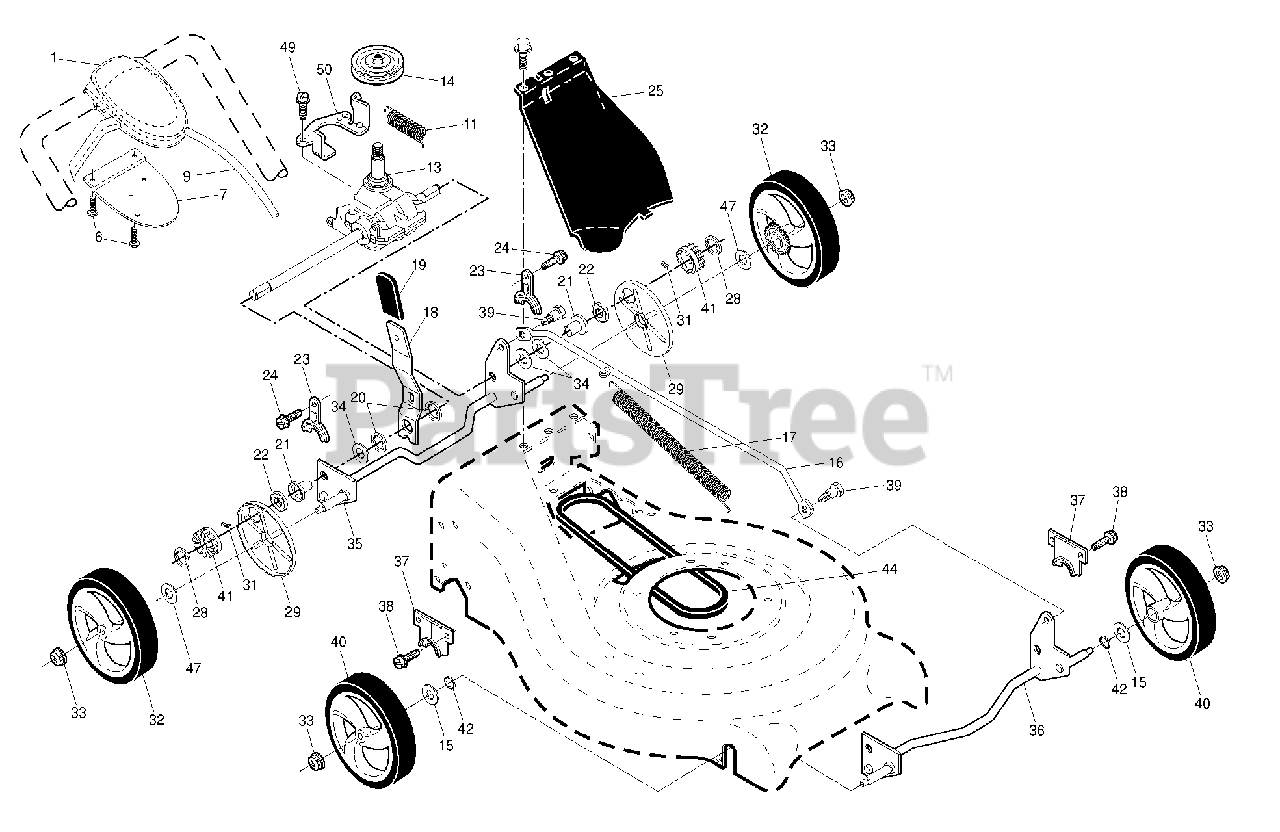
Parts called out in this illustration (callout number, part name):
6	SCREW, PHILLIPS HEAD 10 X 5/8
7	BRACKET.DRIVE.CONTROL.MOUNT
9	CABLE.ASSY.RGD.EZ.AUTO
13	TRANSMISSION.21.RWGD
14	PULLEY.1.PIECE
15	WASHER PM
16	ROD.CONNECTING.SPT.BLACK
17	SPRING EXTENSION
18	SPRING.SELECTOR.
19	KNOB, SELECTOR SPRING
21	BEARING SUPPORT
22	BEARING
23	BRACKET
24	SCREW 14-20 X 5/8
28	E-RING 7/16 RE
29	COVER.DUST.WHEEL
31	PAWL, DRIVE
33	NUT.HEX.FLANGE.3/8-16.LOCKNUT
35	SHAFT ASSY REAR
36	SHAFT ASSY, FRONT
37	RETAINER.FRONT.SHAFT
39	SHOULDER BOLT SEMI GIMLET PT.
41	PINIION.14.TOOTH.RGD
42	O-RING..070X.487.NEOPRENE
44	BELT.RGD.VS
47	WASHER FLUT
50	BELT KEEPER
